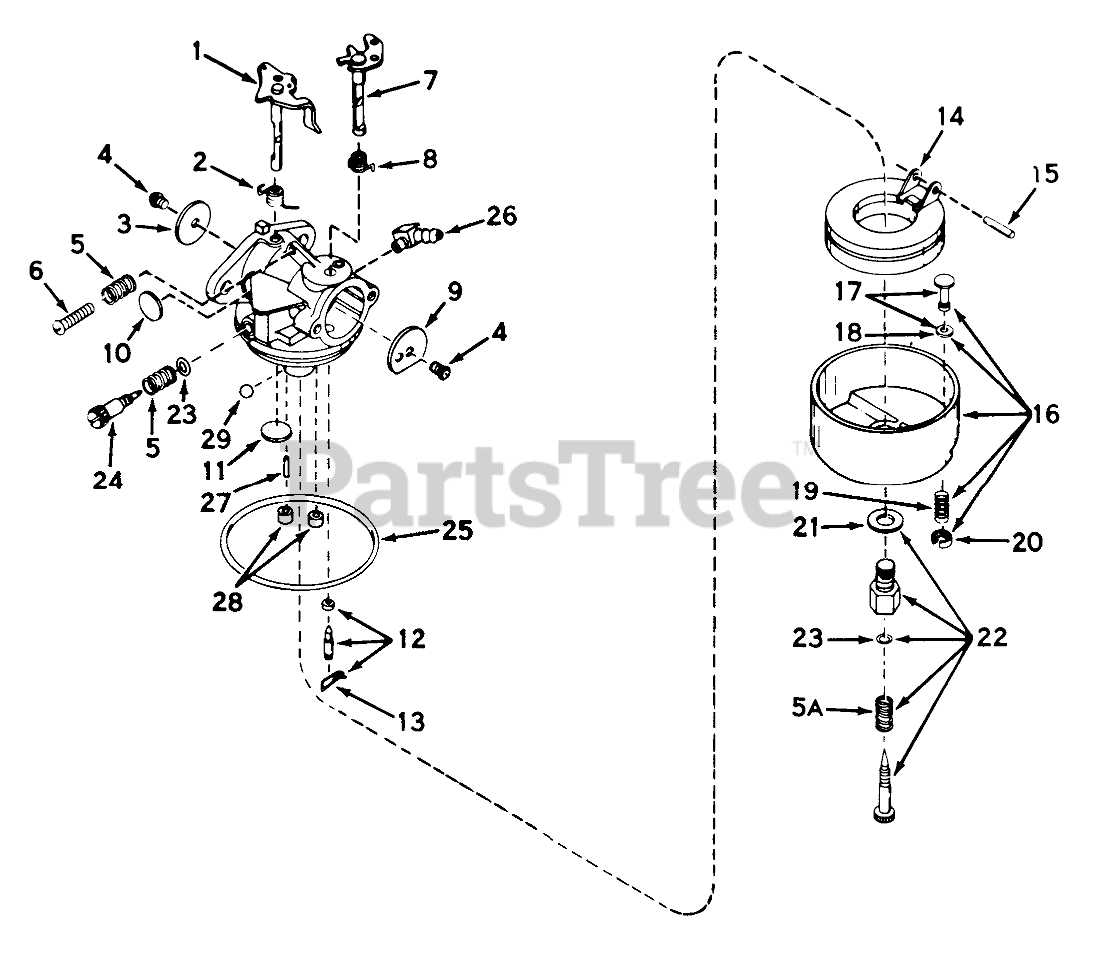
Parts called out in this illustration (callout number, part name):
1	Shaft/Lever-Throttle
2	Spring, Return
3	Shutter-Throttle
4	Screw-Shutter
5	Spring-Tension
6	Screw-Throttle Crack Screw / Idle Speed
7	Shaft& Lever Assy., Choke
8	Spring, Choke return
9	Shutter-Choke
10	Plug-Welch, Idle Mixture Well
11	Plug-Welch, Atmospheric Vent
12	Inlet Needle, Seat & Clip Assy. (Incl. No. 13)
13	Clip-Spring
14	Float,Carburetor
15	Shaft-Float
16	Bowl & Drain Assy., Float (Incl. Nos. 17 thru 20)
17	Plunger Assy., Drain (Incl. No. 18)
18	Gasket-Plunger, Drain
19	Spring, Drain Plunger
20	Retainer, Plunger Spring
21	Washer-Bowl Nut
22	Adjustment Screw Assy., Main (Incl. Nos. 5A, 21, 23 & 30)
23	"O"Ring
24	Screw, Idle Adj.
25	O Ring-Bowl, Float
26	Fitting, Fuel Inlet
28	Plug, Cup
29	BalI, Steel
31	Repair Kit (Incl. items marked)
